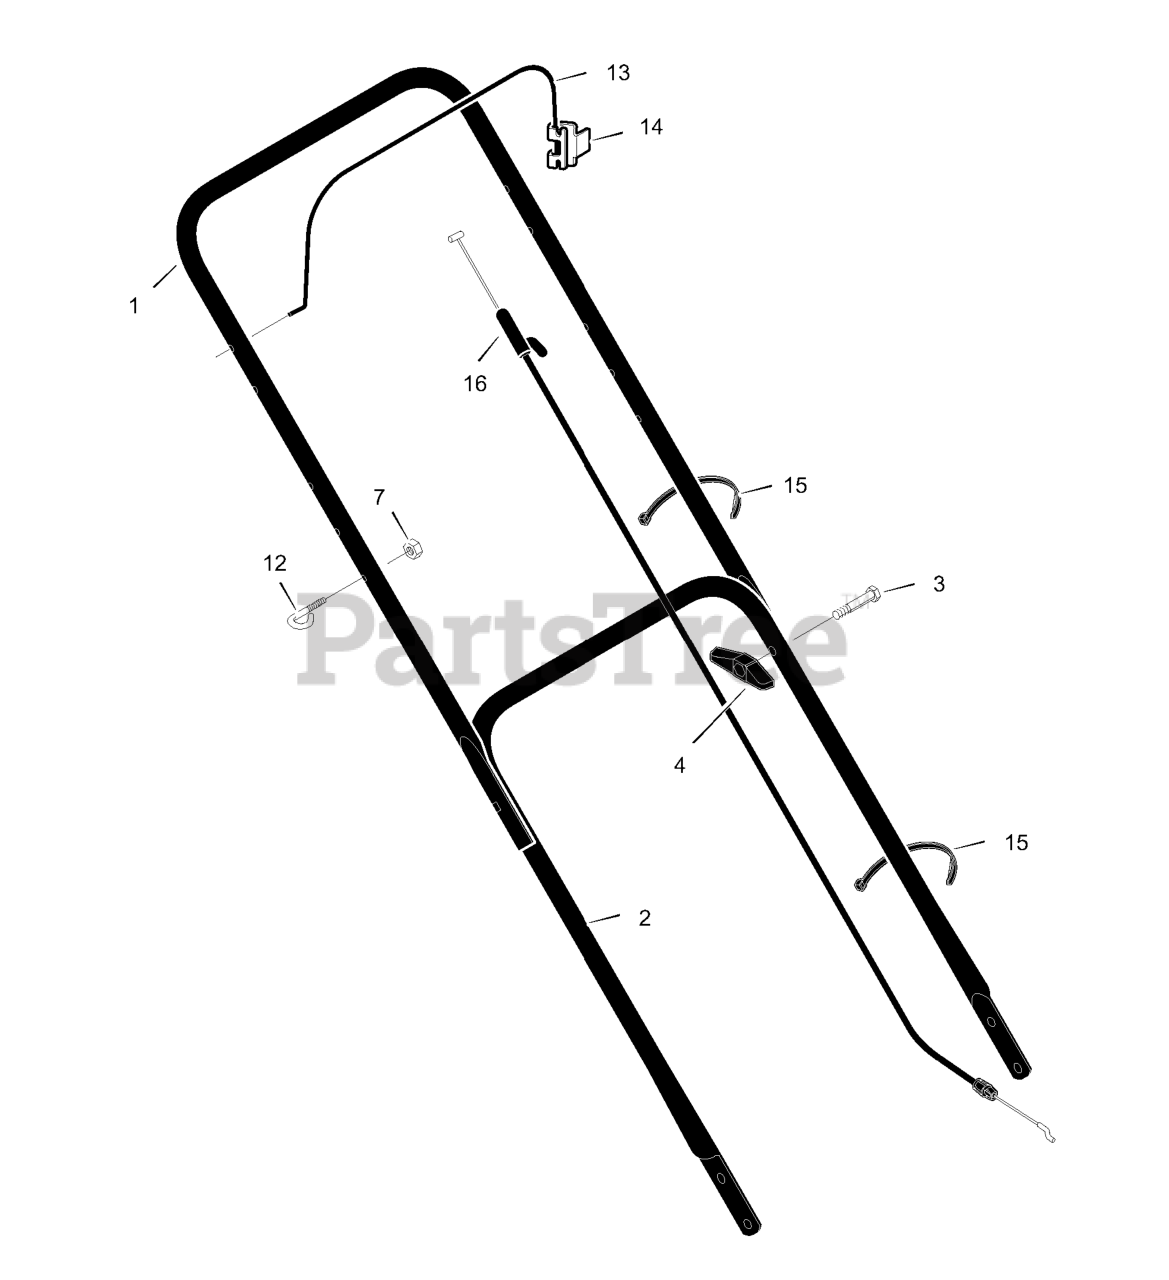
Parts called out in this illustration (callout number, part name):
1	Handle, Upper (Black)
2	Handle, Lower (Black)
4	Knob, Plastic
7	Locknut
12	Guide, Rope
13	Engine Stop Lever
14	Bracket, Stop Lever
15	Fastener, Cable
16	Engine Stop Cable
